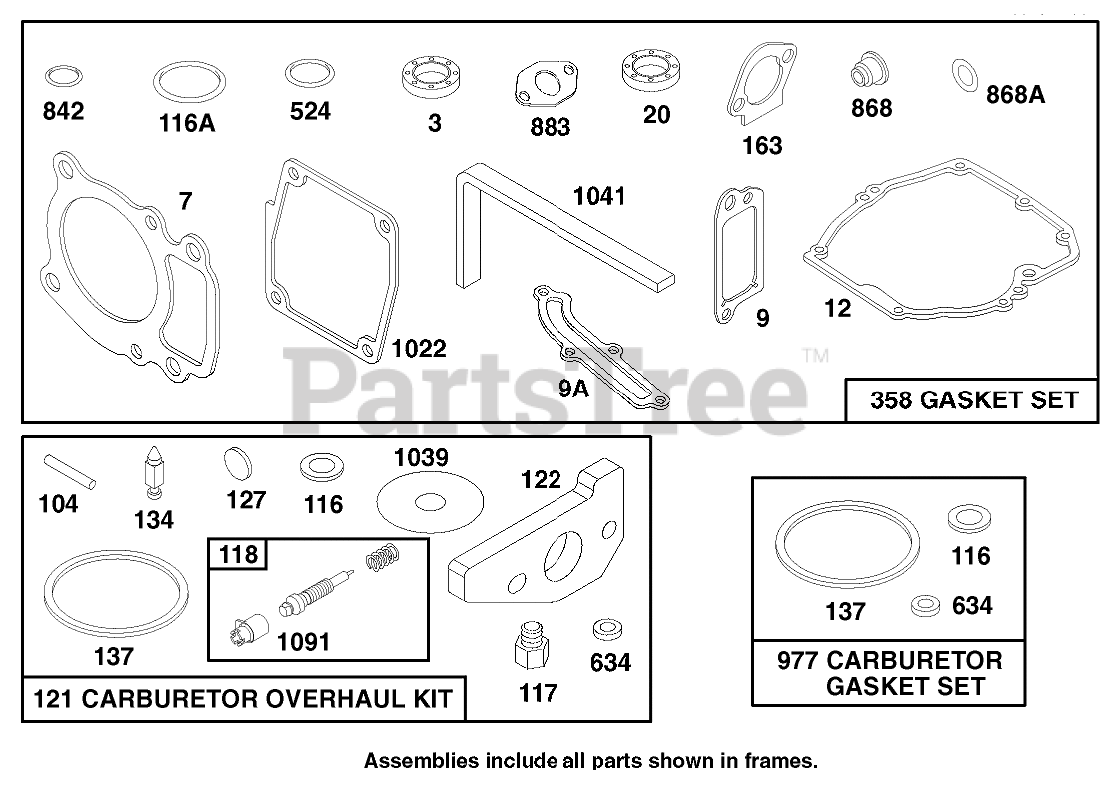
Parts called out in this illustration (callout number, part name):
3	SEAL - OIL
7	CYLINDER HEAD GASKET
9	BREATHER GASKET
9A	GASKET-BREATHER
12	ENGINE BASE GASKET
20	SEAL-OIL
104	FLOAT HINGE PIN
116	SEALING GASKET
116A	O RING SEAL
117	Jet-Main
118	VALVE/SPRING - NEEDLE
121	KIT-CARBURETOR OVERHAUL
122	ADAPTER ASSEMBLY
127	PLUG - WELCH
134	Valve-Inlet (Includes Seat)
137	FLOAT BOWL GASKET
163	AIR CLEANER GASKET
358	GASKET SET
524	O-RING
621	STOP SWITCH
634	SEAL WASHER
842	O-RING
868	SealAssy-Valve
868A	Seal-Valve
883	EXHAUST GASKET
977	CARBURATOR GASKET SET
1022	ROCKER COVER GASKET
1039	FLOAT LIMITER
1041	SEAL - FOAM
1091	CAP - LIMITER
